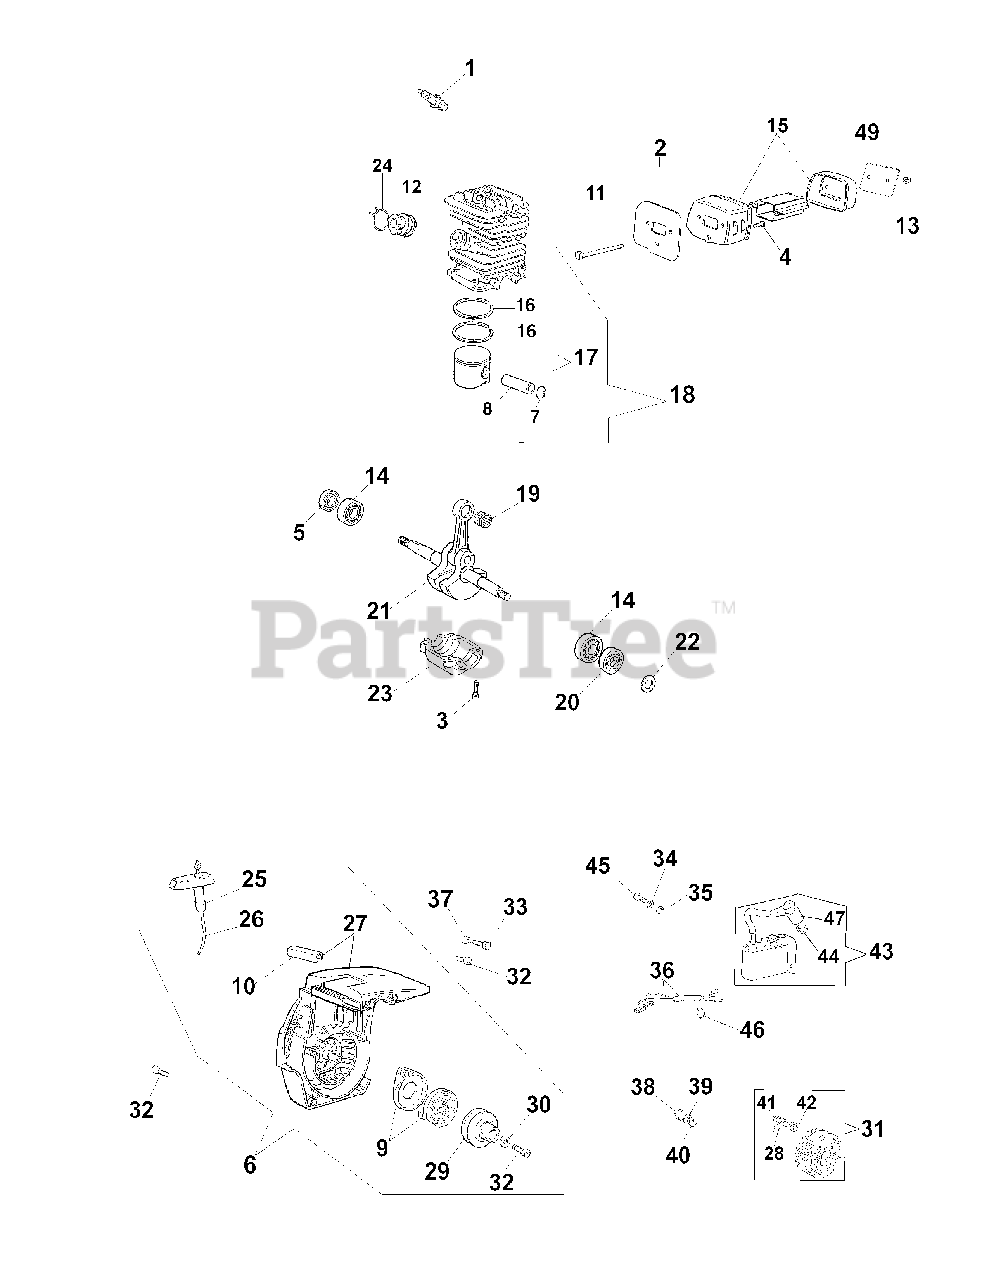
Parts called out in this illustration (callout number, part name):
1	SPARK PLUG
5	SEALING RING
6	STARTER ASSY
9	SPRING and CASE
13	NUT
16	PISTON RING 040
17	COMPL PISTON 040
18	COMPL CYL 040
20	SEALING RING
27	STARTER CASE
28	PAWL
42	SPRING
48	PAWL
49	MUFFLER GUARD
